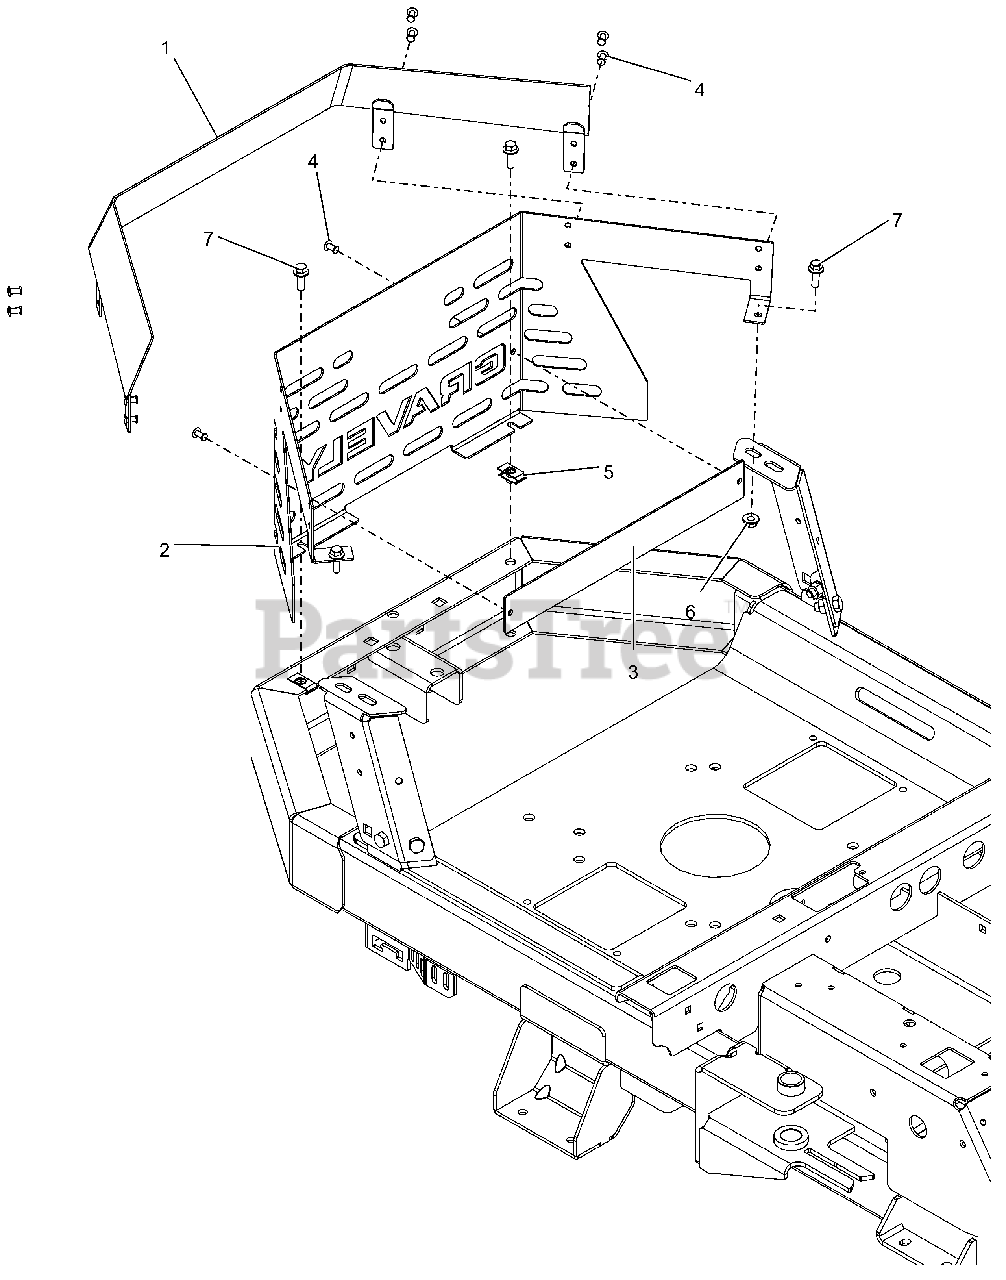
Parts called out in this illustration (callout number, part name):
1	BRACKET, ENGINE SHROUD TRIM
2	SHROUD, ENGINE GRAVELY
3	PLATE, SHROUD BACKER
4	RIVET, #66 STEEL POP PD BLACK
5	NUT-RTNR .25-20X.56
6	NUT-LK-TOP-FLG .250-20 GF ZCC
7	BLT,HEX-FLG .25-20X.75 G5 BFP
